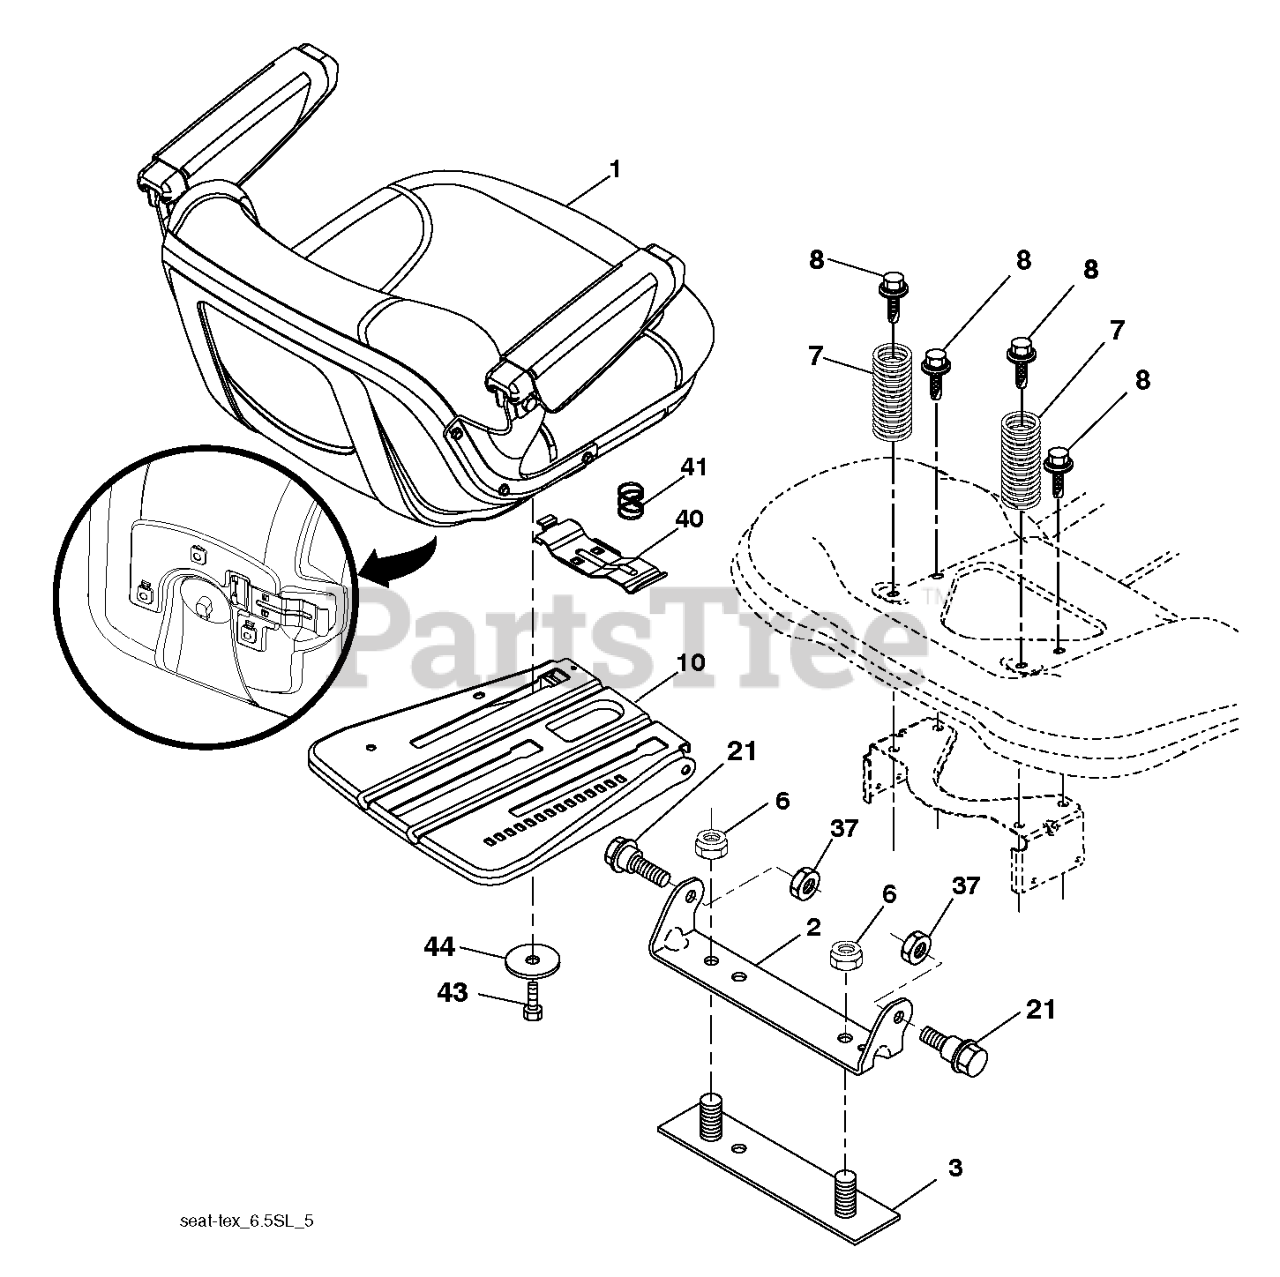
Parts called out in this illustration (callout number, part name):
1	SEAT.TH154.GREY.HUS.ARMREST
2	BRKT.PIVOT.FENDER
3	STRAP
6	NUT
7	SPRING.COMPRESSION.SEAT.BLACK
8	BOLT.5/16-18UNCX3/4 W/SEMS.BLK
10	PAN.ASM.SEAT.3PT
21	BOLT.5/16-18X5/8.SHOULDER
37	NUT.71038.31-18.HEX.NYLOCK
40	HANDLE.SLIDE.SEAT.TEX.GREY
41	SPRING.LATCH.SEAT.TEX
44	WASHER 13/32 X 2-3/8 X 12GA
